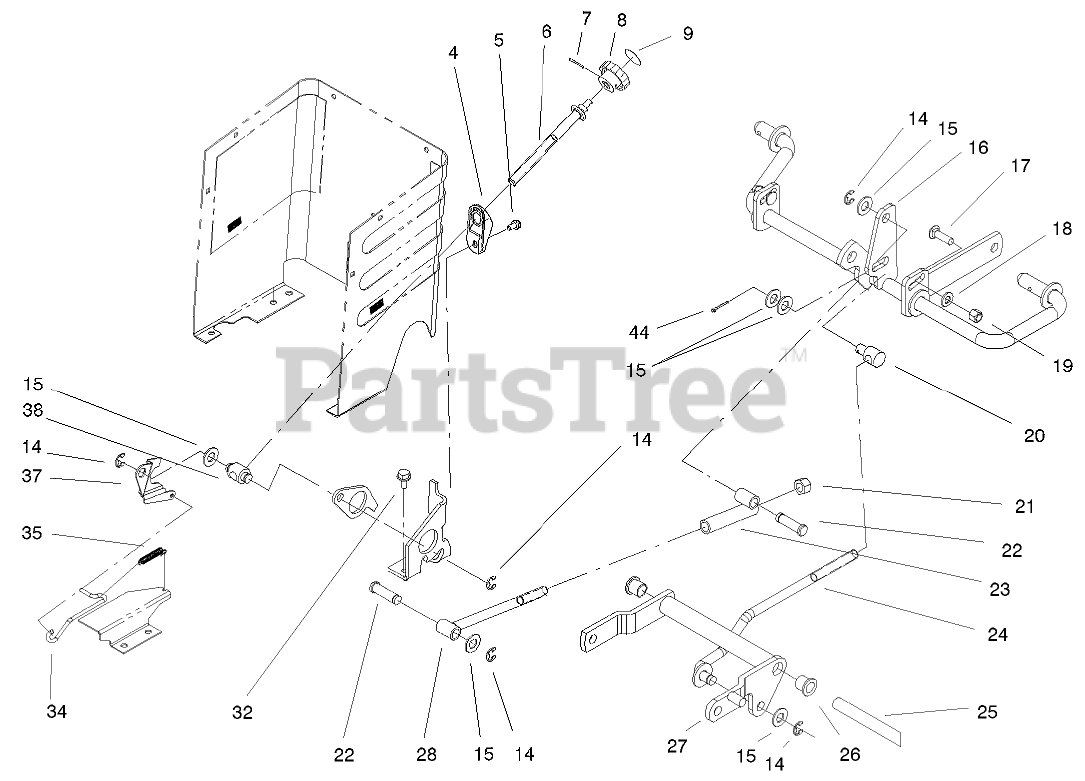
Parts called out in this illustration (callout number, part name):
4	WEDGE - HOC
5	SCREW-HWH
6	ROD - HOC
7	PIN-SPIROL
9	DECAL-HEIGHT KNOB
14	RING-RETAINING, EXTERNAL
15	WASHER-FLAT
16	SHAFT-GAGE
17	BOLT-CARR
18	WASHER-FLAT
19	NUT-LOCK, NI
20	ROD-TRUNNION LIFT
21	NUT-LOCK, NI
25	SHAFT-PIVOT, PEDAL
26	BUSHING-FLANGE
27	ARM-PIVOT
32	SCREW-HWHTF
34	ROD - HOC INDICATOR
35	SPRING - EXTENSION
37	PLATE - HOC GAGE
38	TRUNNION
44	PIN-COTTER
